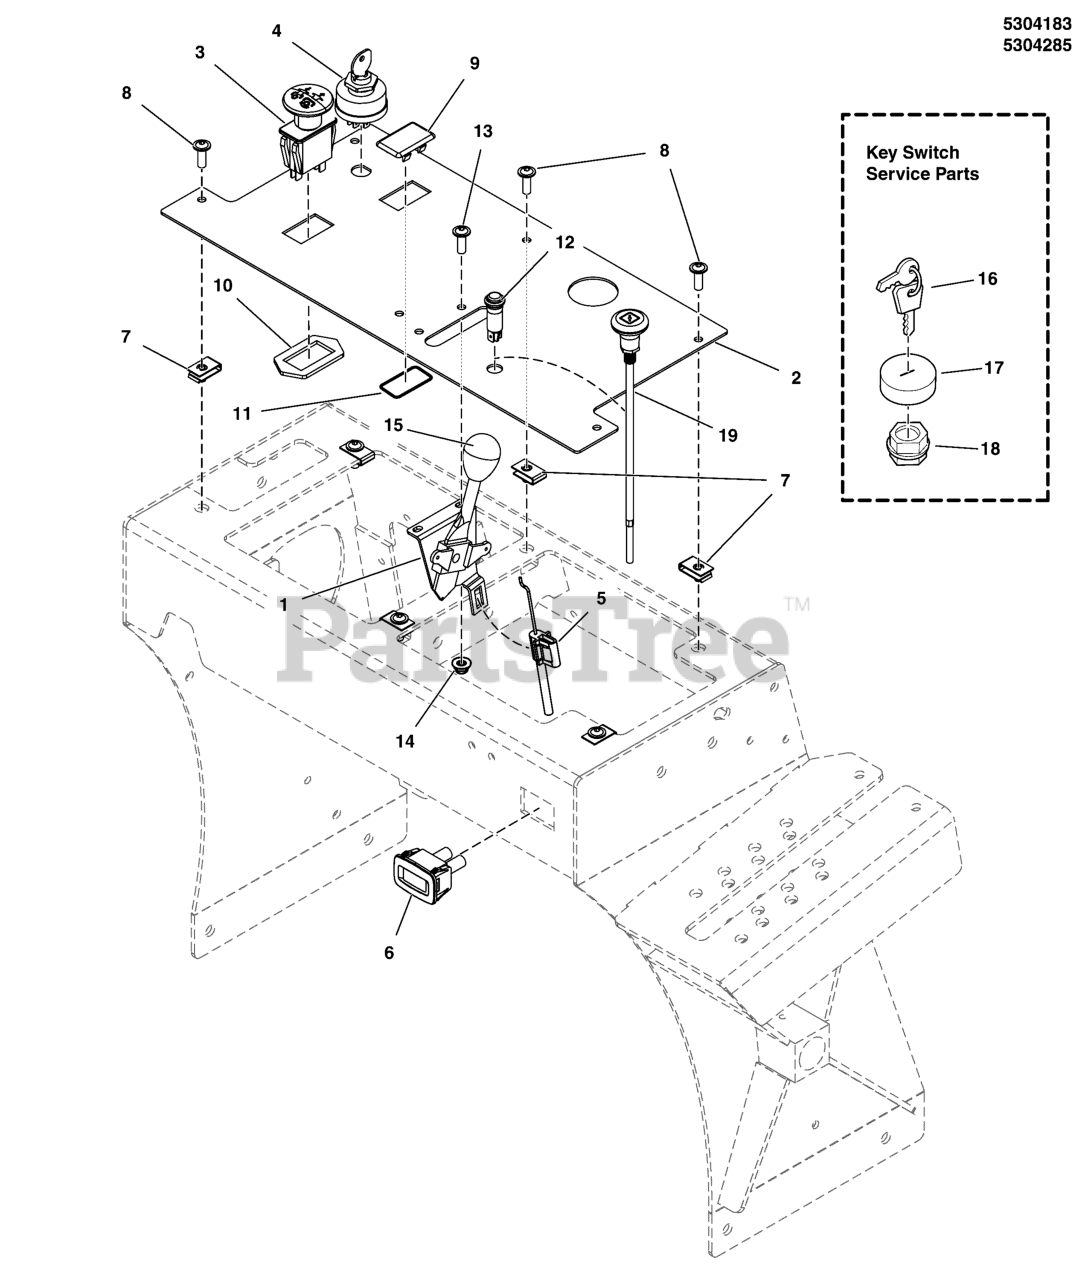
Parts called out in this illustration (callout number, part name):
1	LEVER, HEAVY DUTY, THROTTLE CONTROL
2	DASH PANEL W/DECALS, SRSZ2 (5415654A)
2	DASH PANEL W/DECALS, SRSZ2EFI (5417475A)
3	PTO SWITCH, MOMENTARY, SMALL KNOB
4	SWITCH, IGNITION, 6 POST
5	CABLE, THROTTLE, 40"
6	HOUR METER
7	BODY CLIP, 1/4-20 X 1/2" DEEP
9	PLUG, .820X1.44 HOLE, BLACK PLASTIC
10	RING, SWITCH RETAINER
11	O-RING, 7/8" ID X 1/16" W
12	LIGHT, INDICATOR, PANEL, LED, RED
13	SCREW, #10-24 X 1/2" ROUND PHILLIPS
14	NUT, Hex, Nylon Lock, #10-24
15	THROTTLE CONTROL HANDLE/KNOB
16	KEY, IGNITION MOLDED SET
17	COVER, PLASTIC, SNAP ON
18	PLASTIC NUT
19	CABLE, CHOKE CONTROL, 43.5"
